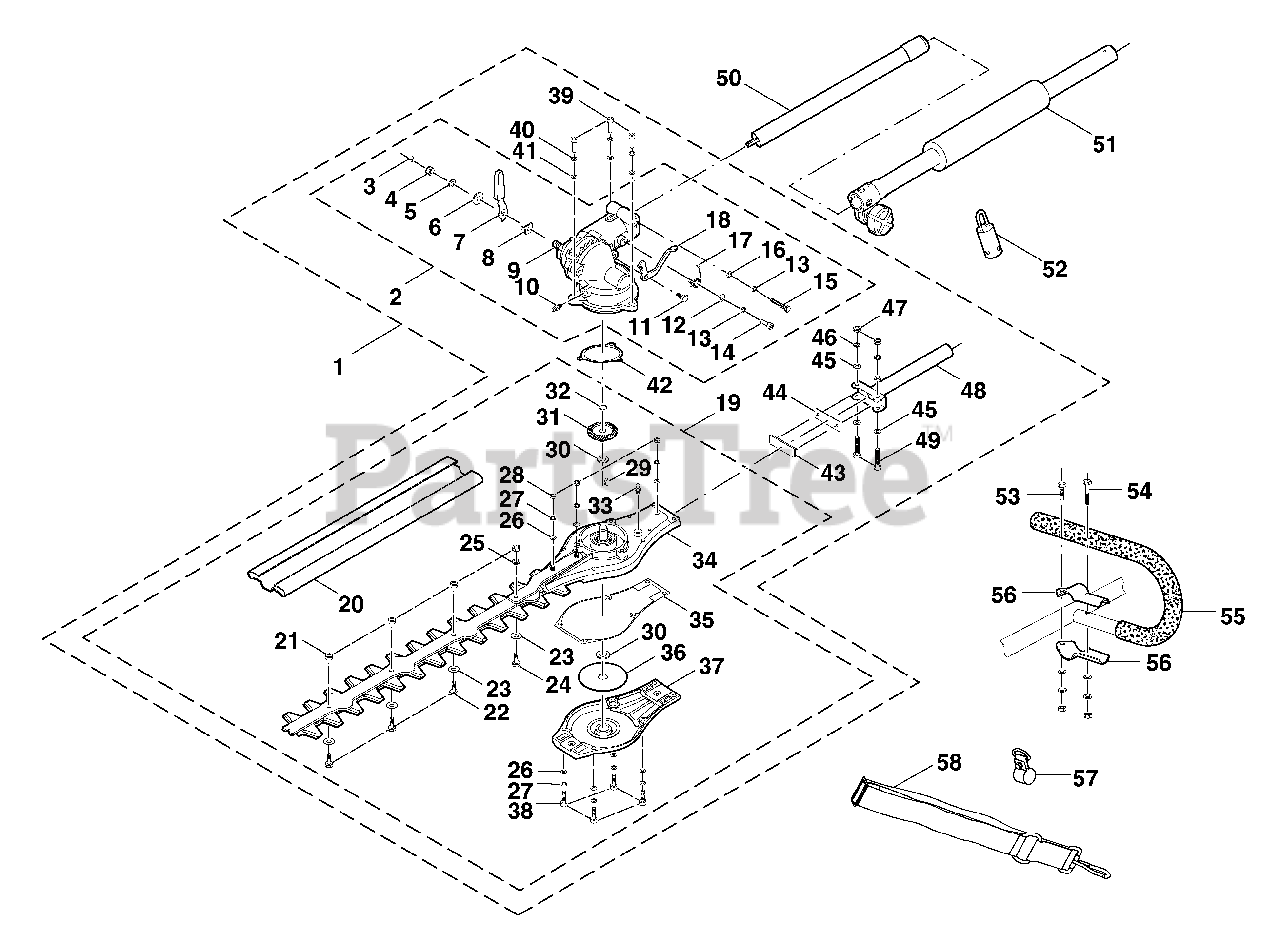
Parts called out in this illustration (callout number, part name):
1	GEARBOX AND BLADE ASSEMBLY
2	UPPER COVER ASSEMBLY
4	HEX NOTCH NUT (M6)
5	SPRING WASHER(ø6)
6	FLAT WASHER (ø6)
7	CLAMPING LEVER
8	LOCKING PLATE
9	ARTICULATING GEARBOX ASSEMBLY
11	LOCKING SCREW (M5)
12	FLAT WASHER
13	SPRING WASHER (ø5)
14	INNER HEX COLUMN HEAD SCREW (M5 X 14 mm)
15	HEX HEAD BOLT (M5 X 30 mm)
16	FLAT WASHER(ø5)
17	RATCHET TORSIONAL SPRING
19	DRIVEN GEAR HOUSING AND BLADE ASSEMBLY W/ BACK COVER
20	BLADE GUARD
21	LOCKING NUT (M6)
22	HEX HEAD BOLT (M6 X 16 mm)
23	FLAT WASHER (ø6)
24	HEX HEAD BOLT (M6 X 22 mm)
25	SPRING WASHER (ø6)
26	FLAT WASHER (ø5)
27	SPRING WASHER (ø5)
28	HEX NUT (M5)
29	HALF-ROUND KEY
30	ADJUST SPACER
31	DRIVEN BEVEL GEAR
32	C-RING (ø10)
34	DRIVEN GEAR HOUSING AND BLADE ASSEMBLY W/O BACK COVER
36	CIRCLE GUARD PLATE
37	BACK COVER ASSEMBLY
38	INNER HEX COLUMN HEAD SCREW (M5 X 20 mm)
39	INNER HEX COLUMN HEAD SCREW (M5 X 16 mm)
40	SPRING WASHER (ø5)
41	FLAT WASHER (ø5)
43	RUBBER SEAL
44	METAL PLATE
45	FLAT WASHER (ø5)
46	SPRING WASHER (ø5)
47	HEX NUT (M5)
48	LOWER HANDLE ASSEMBLY
49	HEX HEAD BOLT (M5 X 30 mm)
50	LOWER BOOM ASSEMBLY
51	INTERMEDIAL BOOM ASSEMBLY
52	HANGER
53	BOLT ASSEMBLY (SHORT)
54	BOLT ASSEMBLY (LONG)
55	J-HANDLE AND GRIP
56	HANDLE BAR CLAMP
57	STRAP HANGER
58	SHOULDER STRAP ASSEMBLY
